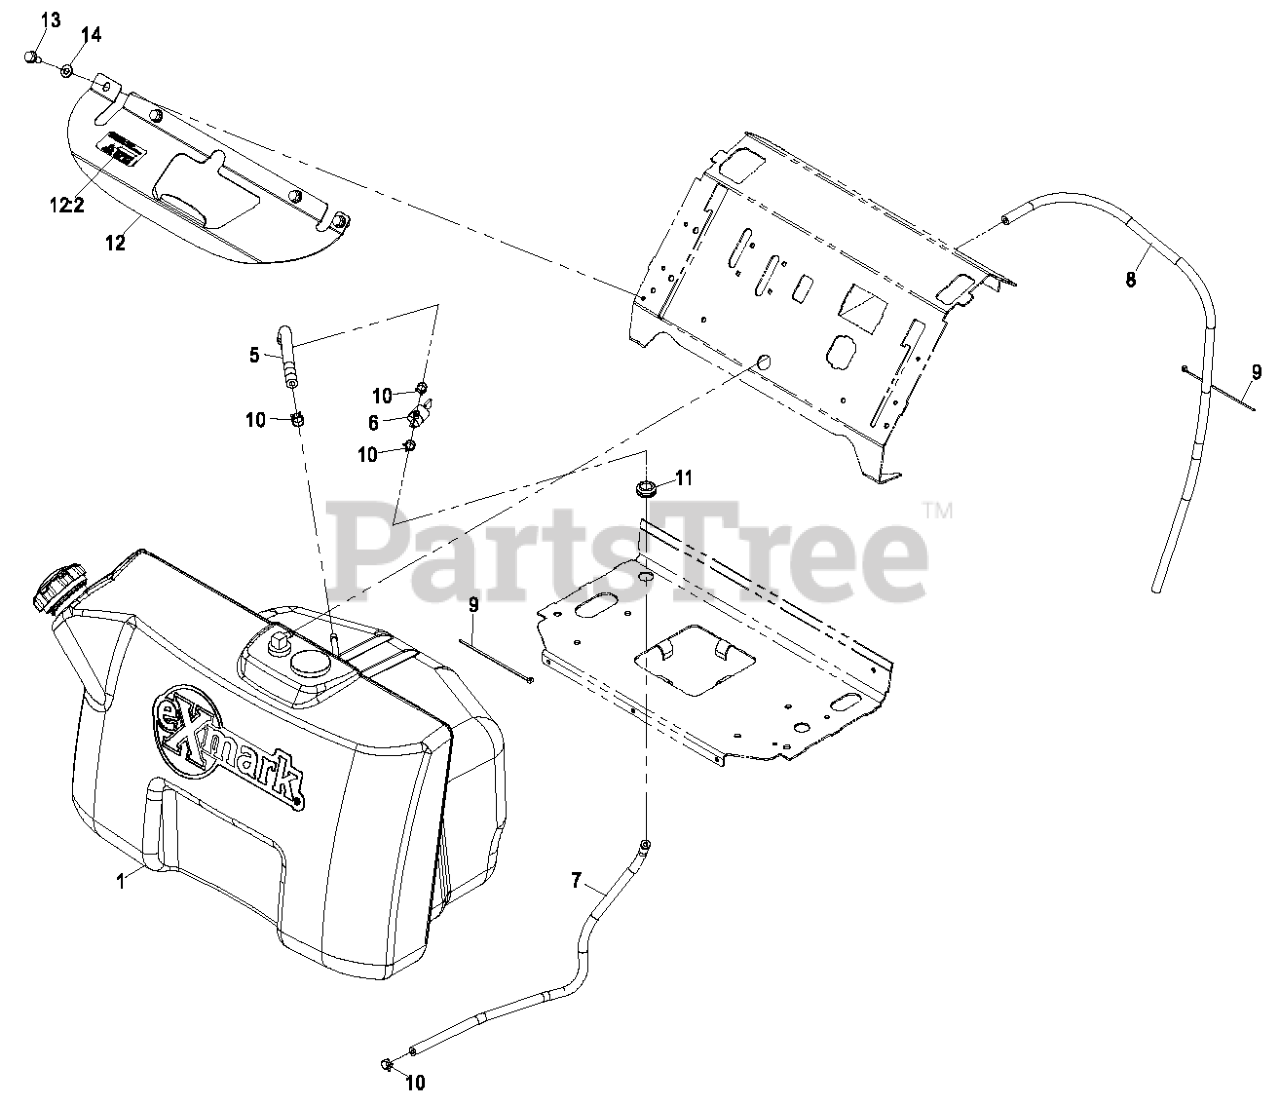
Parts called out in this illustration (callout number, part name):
5	HOSE-FUEL
6	VALVE-FUEL
7	HOSE-FUEL
8	HOSE-FUEL
9	TIE-CABLE
10	CLAMP-HOSE
11	GROMMET
12	BRACKET-TANK
12:2	DECAL-FILL, FUEL
13	SCREW-THD ROLL, HWH
14	WASHER-FLAT
